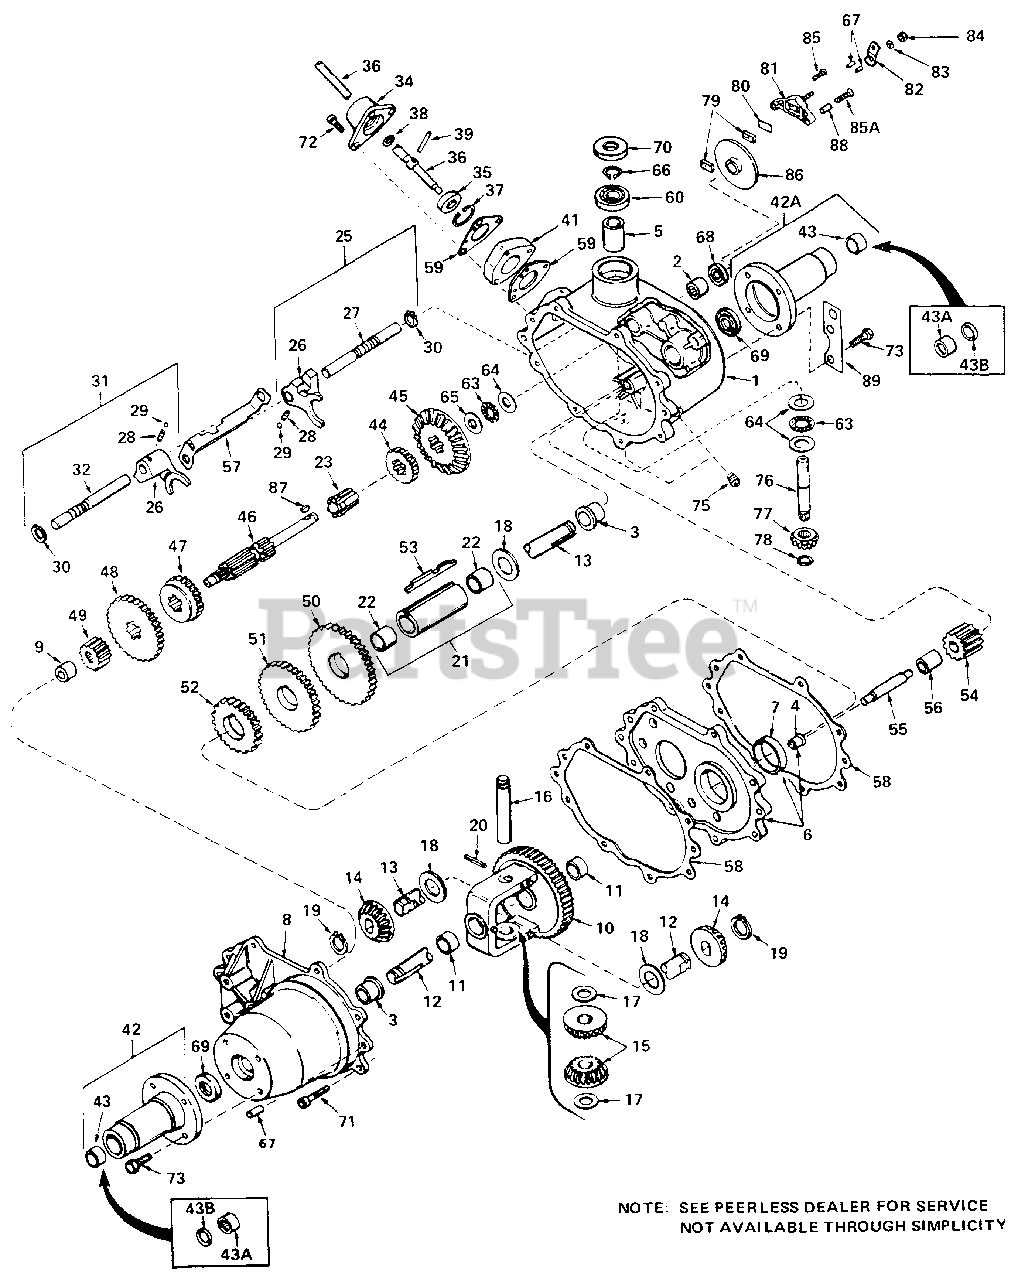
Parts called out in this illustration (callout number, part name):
1	CASE ASSEMBLY, Transaxle (Incl. Nos. 2, 3, & 5)
2	BEARING, Needle
3	BEARING, Bronze
4	BEARING, Bronze
5	BEARING, Bronze
6	PLATE ASSEMBLY, Center (Incl. Nos. 4 & 7)
7	BEARING, Bronze
8	COVER ASSEMBLY, Transaxle (Incl. Nos. 3 & 9)
9	BEARING, Needle
10	GEAR ASSEMBLY, Differential (Incl. No. 11)
11	BEARING, Bronze
12	AXLE, L.H.
13	AXLE, R.H.
14	GEAR, Bevel
15	PINION, Bevel
16	PIN, Drive
17	WASHER, Thrust
18	WASHER, Thrust
19	RING, Snap
20	PIN, Roll
21	SLEEVE ASSEMBLY, Countershaft (Incl. No. 22)
22	BEARING, Bronze
23	SHAFT, Idler
25	ROD ASSEMBLY, Shift (1st & Rev.)(Incl. No. 26-30)
26	FORK, Shift
27	ROD, Shift
29	BALL, Steel
30	RING, Snap
31	ROD ASSEMBLY, Shift (2nd & 3rd)(Inc. Nos. 26, 28, 29, 30, & 32)
32	ROD, Shift
34	HOUSING, Shift Lever
35	KEEPER, Shift Lever
36	LEVER, Shift
37	RING, Snap
38	RING, Quad
39	PIN, Drive
41	BLOCK, Riser
42	HOUSING ASSEMBLY, Axle (Incl. No. 43)
42A	HOUSING ASSEMBLY, Axle (Incl. No. 43)
43	BEARING & SEAL ASSEMBLY, Needle (See Note 1)
43A	BEARING, Needle
43B	SEAL, Oil
44	GEAR (16 Teeth)
45	GEAR, Bevel (33 Teeth)
46	SHAFT, Shifter and Brake
47	GEAR, Shifting (2nd and 3rd)
48	GEAR, Shifting (1st and Rev.)
49	GEAR, Spur (12 Teeth)
50	GEAR, Countershaft Drive (39 Teeth)
51	GEAR, Countershaft (34 Teeth)
52	GEAR, Countershaft (25 Teeth)
53	KEY, Countershaft
54	IDLER, Reverse
55	SHAFT, Reverse Idler
56	SPACER, Reverse Idler
57	STOP, Shifter
58	GASKET, Case and Cover
59	GASKET, Shift Lever Housing
60	BEARING, Ball
63	BEARING, Thrust
64	WASHER, Thrust
65	WASHER, Thrust
66	RING, Snap
67	PIN, Dowel
68	SEAL, Oil
69	SEAL, Oil
70	SEAL, Oil
71	CAPSCREW, Socket Hd., 1/4-20 x 1 1/4
72	CAPSCREW, Socket Hd., 1/4-20 x 1 3/4
73	SCREW, Hex Hd., Sems, 5/16-18 x 1
75	PLUG, Pipe, 1/8
76	SHAFT, Input
77	PINION, Input
78	RING, Retaining
79	PAD, Brake
80	PLATE, Brake Pad
81	HOLDER, Brake Pad
82	LEVER, Brake
83	WASHER, Flat
85	CAPSCREW, Hex Hd., Thread Forming, 1/4-20 x 1 1/4
85A	SCREW, Hex Hd., Thread Forming, 1/4-20 x 2 1/4
86	DISK, Brake
87	KEY, Woodruff No. 61
89	BRACKET, Spring Anchor
